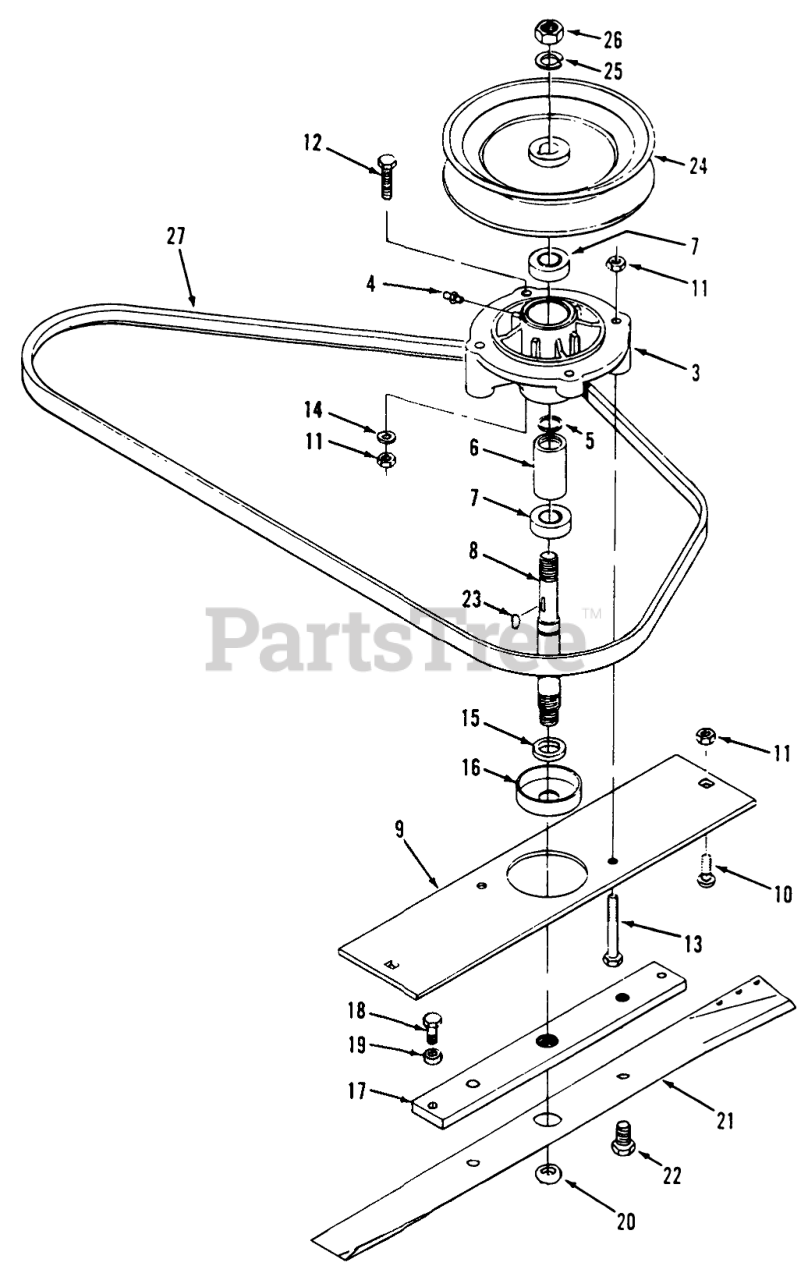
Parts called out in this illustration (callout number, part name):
3	HOUSING-SPINDLE
4	Fitting-Grease
5	SNAP RING
7	BALL BEARING
8	SHAFT
9	BAR R
10	Bolt
11	NUT
12	Bolt
13	Bolt
14	Washer
15	SPACER-BLADE
16	CUP-SPINDLE
17	BAR-BLADE R
18	Bolt
19	NUT-HEX, JAM
20	Nut
21	Blade
22	HEX BOLT 1/2-13X3/4
23	KEY-HI-PRO
24	PULLEY HUB ASSY
25	Lockwasher
26	Nut
27	V-BELT DRIVE
